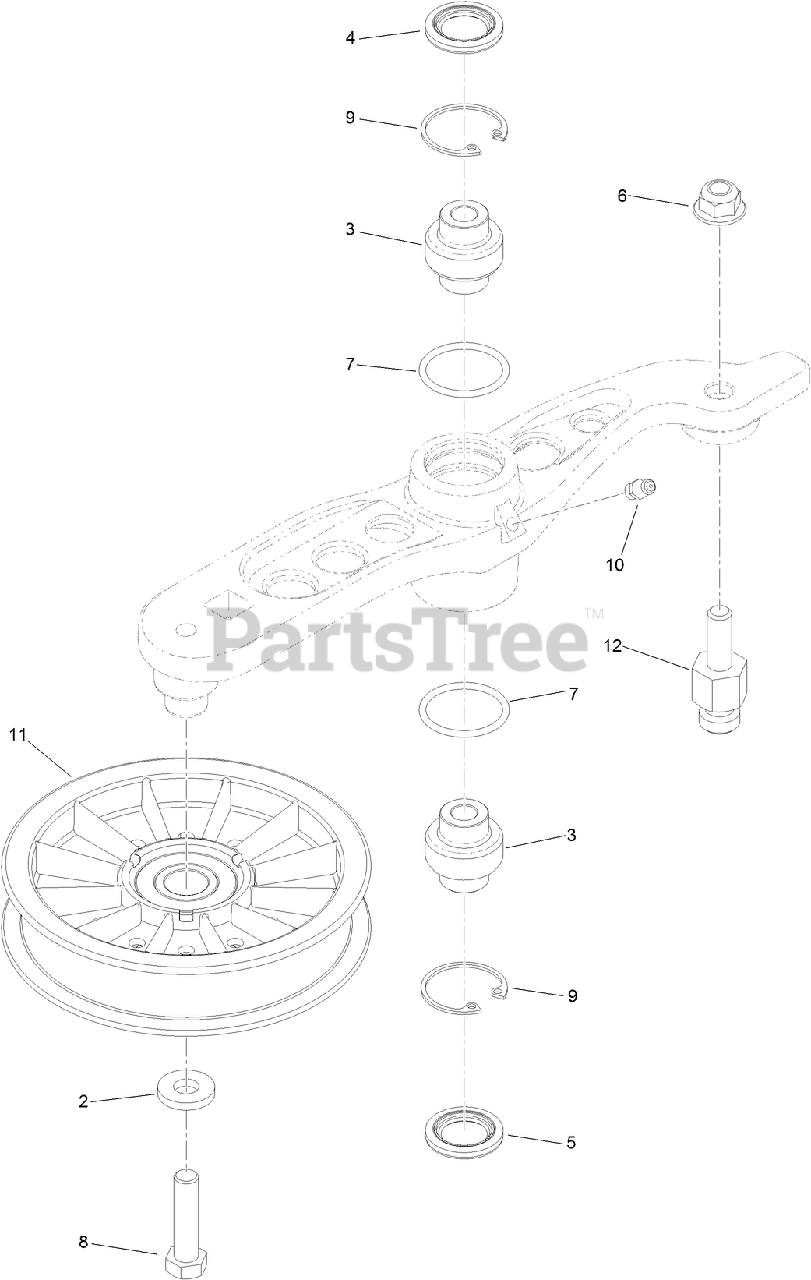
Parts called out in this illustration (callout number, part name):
2	SPACER
3	BEARING-SPHERICAL
4	SEAL-LIP, DOUBLE
5	SEAL-LIP, SINGLE
6	NUT-FLANGE, NI
7	O-RING
8	SCREW-HH
9	RING-SNAP
10	FITTING-GREASE
11	PULLEY-IDLER
12	PIN-ANCHOR, SPRING
